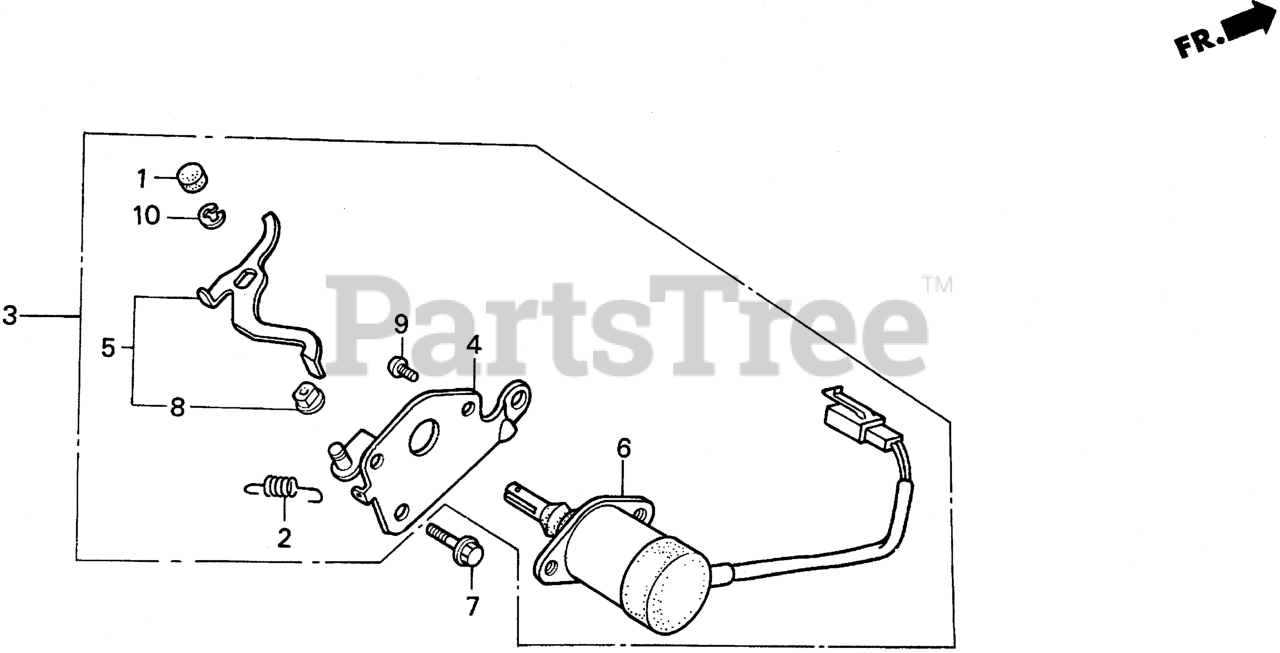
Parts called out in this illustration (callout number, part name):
1	CAP, CHOKE LEVER
2	SPRING, CHOKE RETURN
3	THROTTLE ASSY., AUTO
3	AUTO-THROTTLE ASSY.
4	STAY, SOLENOID THROTTLE
5	LEVER, SOLENOID THROTTLE
6	SOLENOID ASSY.
7	BOLT, FLANGE (6X12) (CT200)
8	BUSH, AUTO-THROTTLE LEVER
9	SCREW, PAN (5X8)
10	E-RING (4MM)
